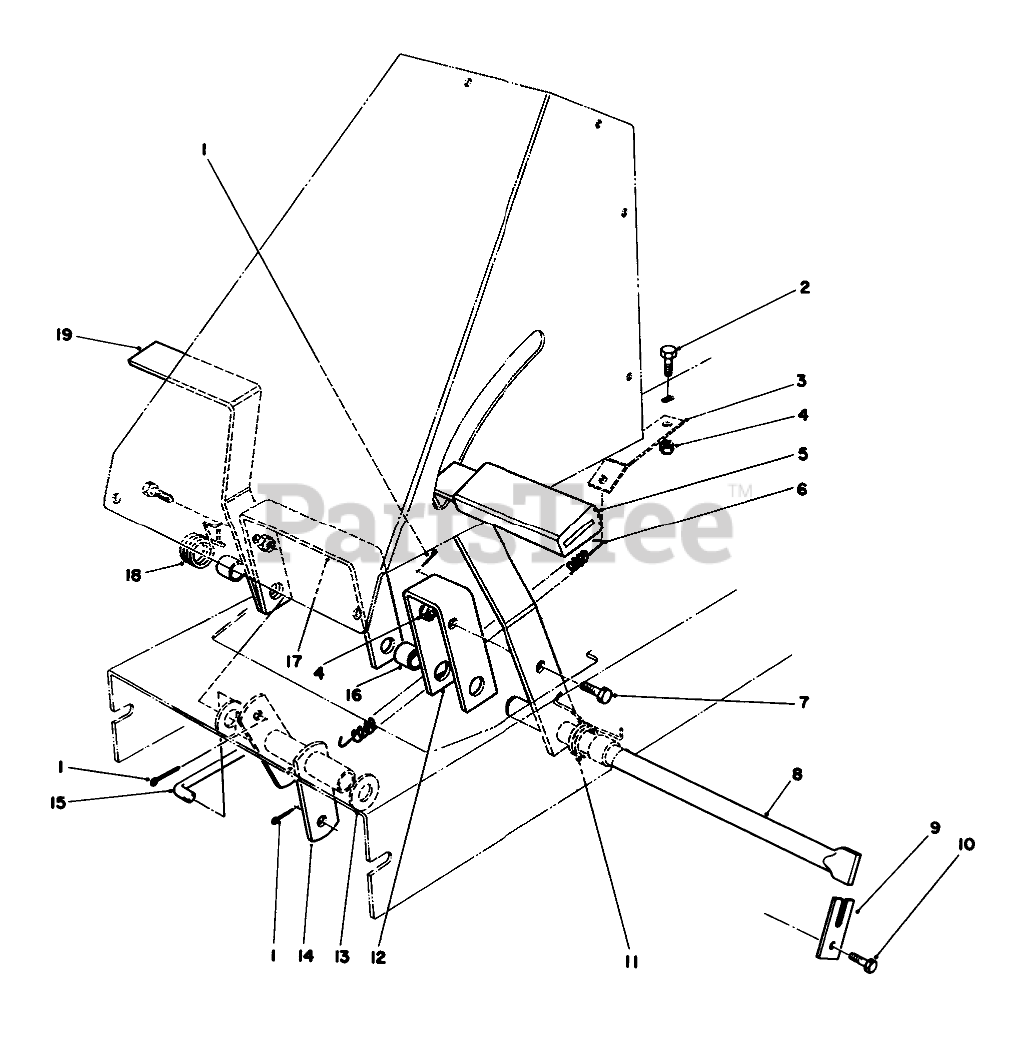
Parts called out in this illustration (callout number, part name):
1	PIN-COTTER
2	SCREW-HH
3	BRKT-SPRING RET
4	NUT-LOCK, NI
5	Pad-Foot Pedal
6	TRACTION SPRING
7	SCREW-HH
8	SHAFT-PEDAL PIVOT
9	RETAINER-SHAFT
10	SCREW-HH
11	SPRING-TORS CLUTCH
12	Bracket-Clutch Pedal
13	WASHER-FLAT
14	Pivot Tube
15	ROD-ENGAGE
16	SPACER-PEDAL
17	Bracket-Brake Pedal
18	SPRING-TORS BRAKE
19	Pedal
